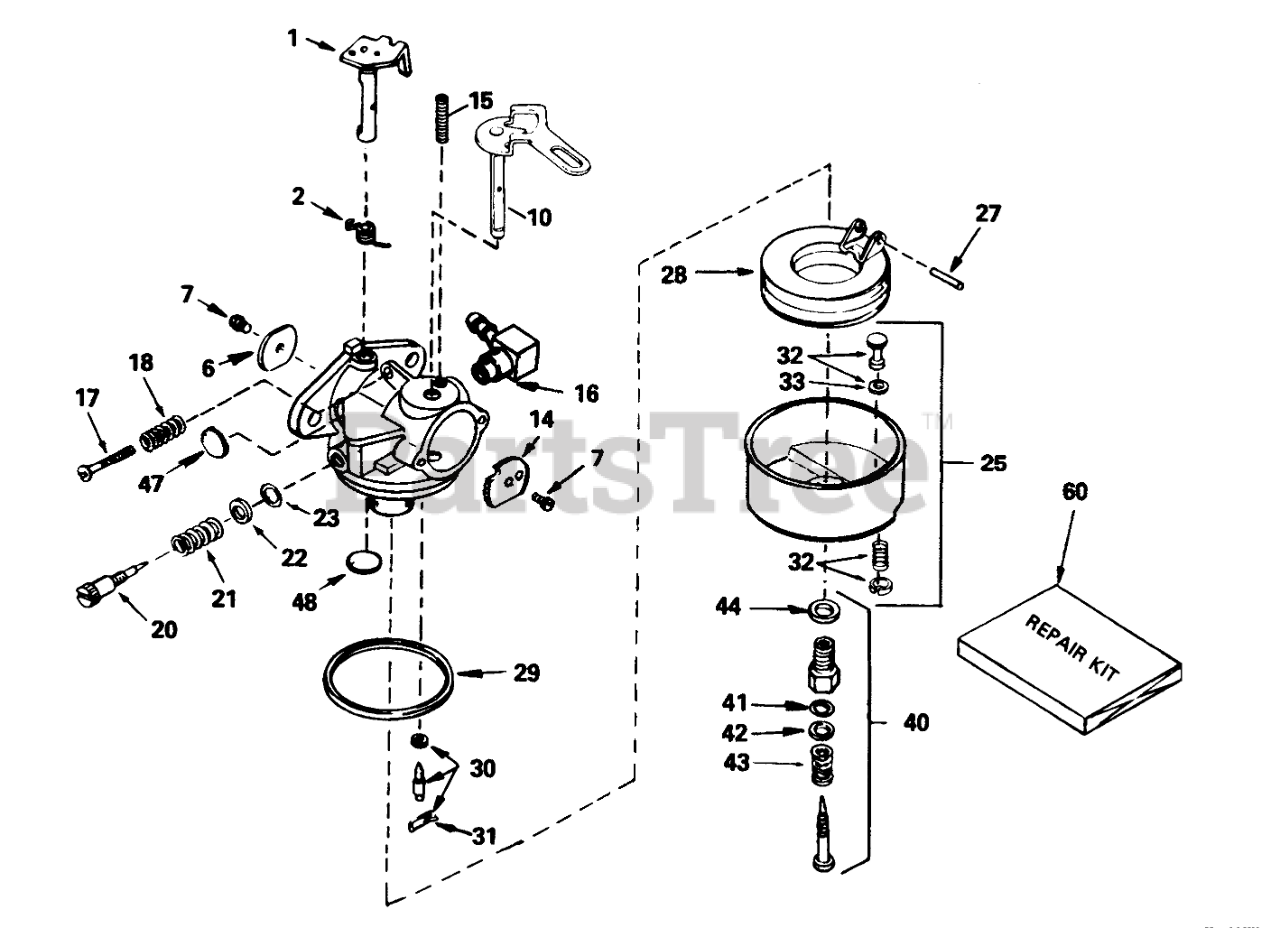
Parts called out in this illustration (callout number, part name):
1	Throttle Shaft and Lever ASM
2	Spring-Return, Throttle
6	Shutter-Throttle
7	Screw-Shutter
10	Choke Shaft and Lever Asm
14	Shutter-choke
15	Spring-Positioning, Choke
16	Fitting-Fuel
17	Screw-Throttle Crack Screw / Idle Speed
18	Spring-Tension
20	Screw-Idle
21	Spring-Tension
23	"O"Ring
25	Bowl-Assembly (Incl. Ref. #32 & 33)
27	Shaft-Float
28	Float
29	O Ring-Bowl, Float
30	Inlet Needle-Seat & Clip (Incl. Ref. #31)
31	Clip-Spring
32	Drain Assembly-Bowl (Incl. Ref. #33)
33	Gasket-Plunger, Drain
40	Screw Adjustment Assembly (Incl. Ref. #41-44)
41	"O"Ring
44	Washer-Bowl Nut
47	Plug-Welch, Idle Mixture Well
48	Plug-Welch, Atmospheric Vent
60	Kit-Repair
